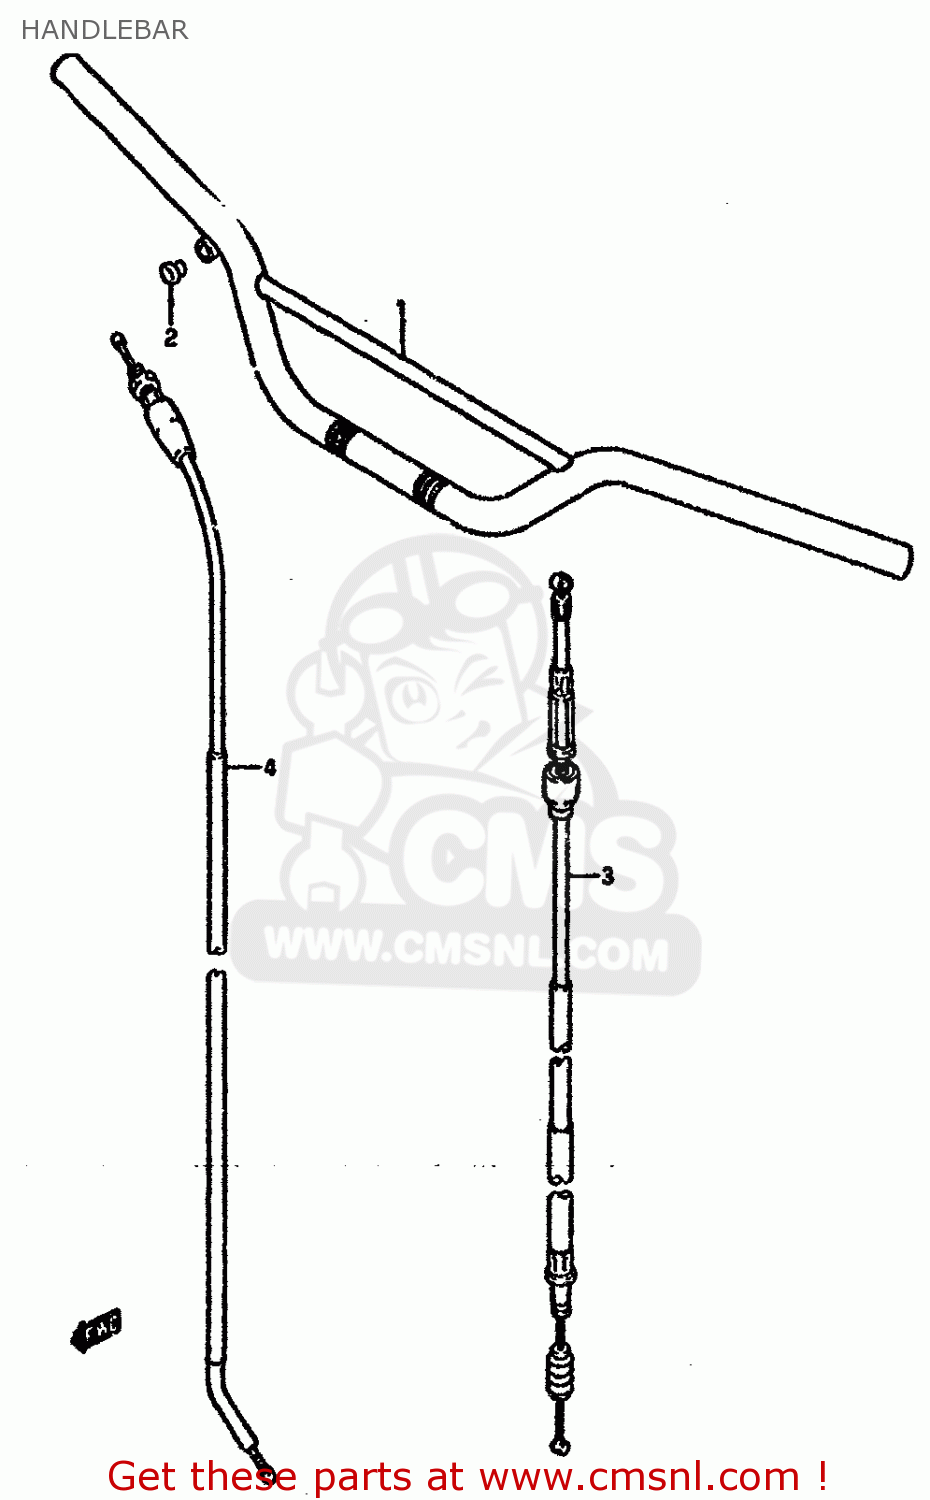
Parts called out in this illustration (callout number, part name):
1	HANDLEBAR
2	CAP(OD:14)
3	CABLE ASSEMBLY,CLUTCH
4	CABLE ASSEMBLY,THROTTLE
